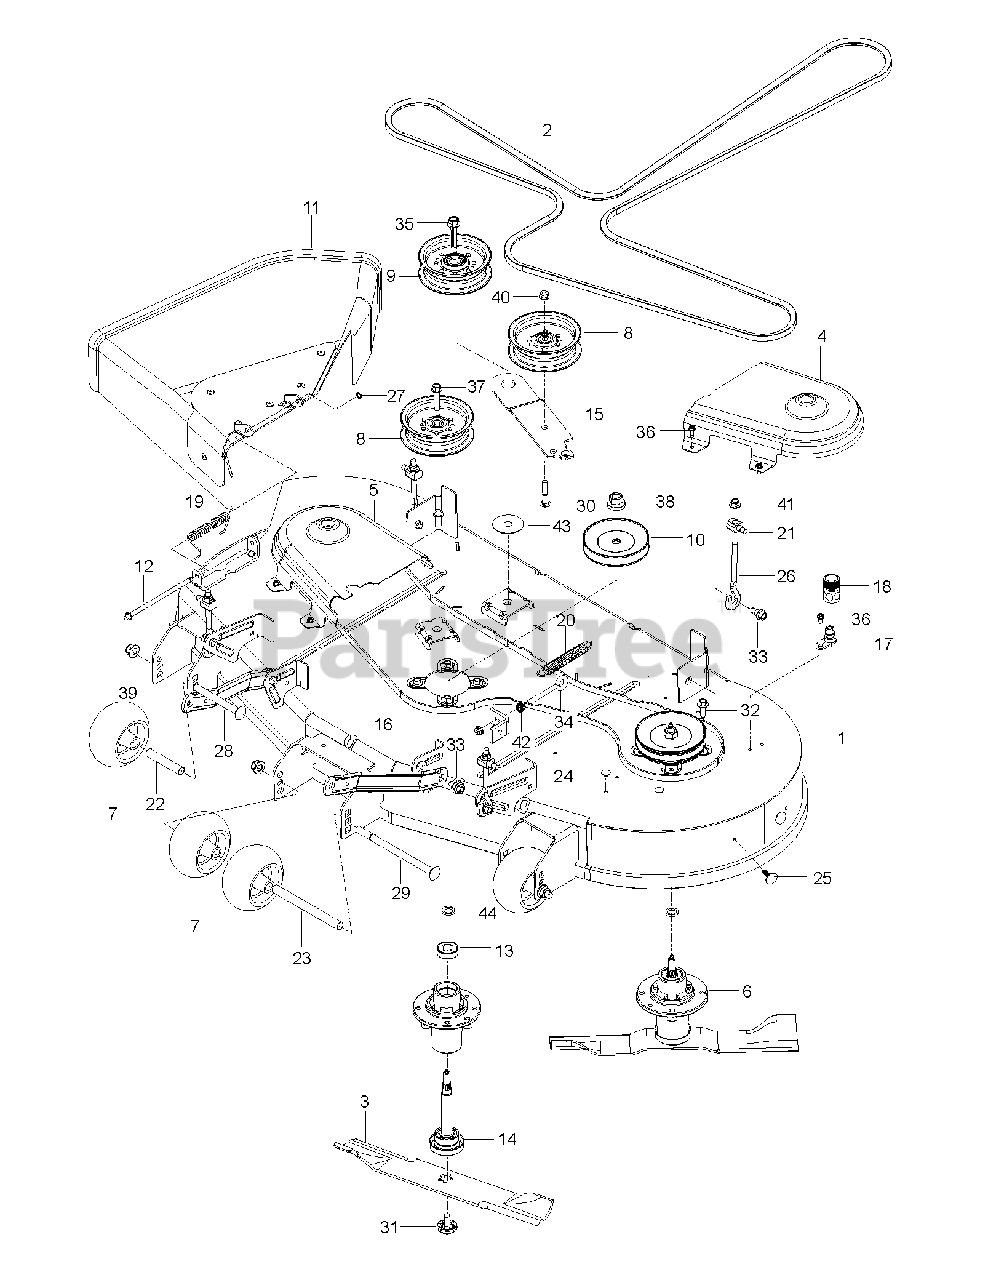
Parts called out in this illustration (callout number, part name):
1	DECK.54W/SFTY.DCLS.CC.BLACK428
2	BELT CLEARCUT 54, MZ DECK DRIV
3	BLADE CC54 PZ STYLE HIGH LIFT,
4	Mandrel Cover, 54" Clearcut, LH
5	Mandrel Cover, 54" Clearcut RH B
6	MANDREL ASM, CAST IRON
7	ROLLER, GAUGE .635 BORN
8	PULLEY.IDLER.2006
9	RB PULLEY.IDLER.4.50/HUB SPEC
10	PULLEY.MANDREL.CRD 107CM.DOM.
11	DEFLECTOR ASSY 54 CLEARCUT RES
12	ROD.HINGE
14	SHAFT ASM MANDREL
15	ARM IDLER ARM, CLEARCUT 54 BLA
16	ARM.SUSPENSION.MOWER
17	PORT.WASHOUT
18	COUPLING.QUICK CONNECT
19	SPRING.42.FCS.DEFLECTOR
20	SPRING.MOWER.DRIVE.ELECTRIC
21	TRUNNION
22	TUBE, ROLLER AXLE
23	TUBE, ROLLER AXLE LONG
24	PLUG CHRISTMAS TREE
25	FASTENER.XMAS.TREE
26	LINK.ADJUSTABLE
27	NUT PUSH M
28	RHSNB 1/2-13 X 4.75 GR5 ZD
29	RHSNB 1/2-13 X 8 GR5 ZD
30	BOLT
31	BOLT.WASHER.ASM.7/16-2
32	BOLT.HEX.WASHR.HED.313-18X1.19
33	BOLT.SHOULDER
34	EYE BOLT 5/16 X 3.50
35	SCREW.7/16-14 X 2.125.WASHER
36	SCREW.1/4-20X5/8
37	SCREW LT
38	NUT.FLANGE.LOCK.TOP
39	NUT, 1/2-13 HEX FLG NYLOC ZD
40	NUT LOCK FLG 3/8-16 UNC
41	NUT.FLANGE.LOCK
42	NUT 5/16C WHIZ
44	WASHER.SPACER.MANDREL
